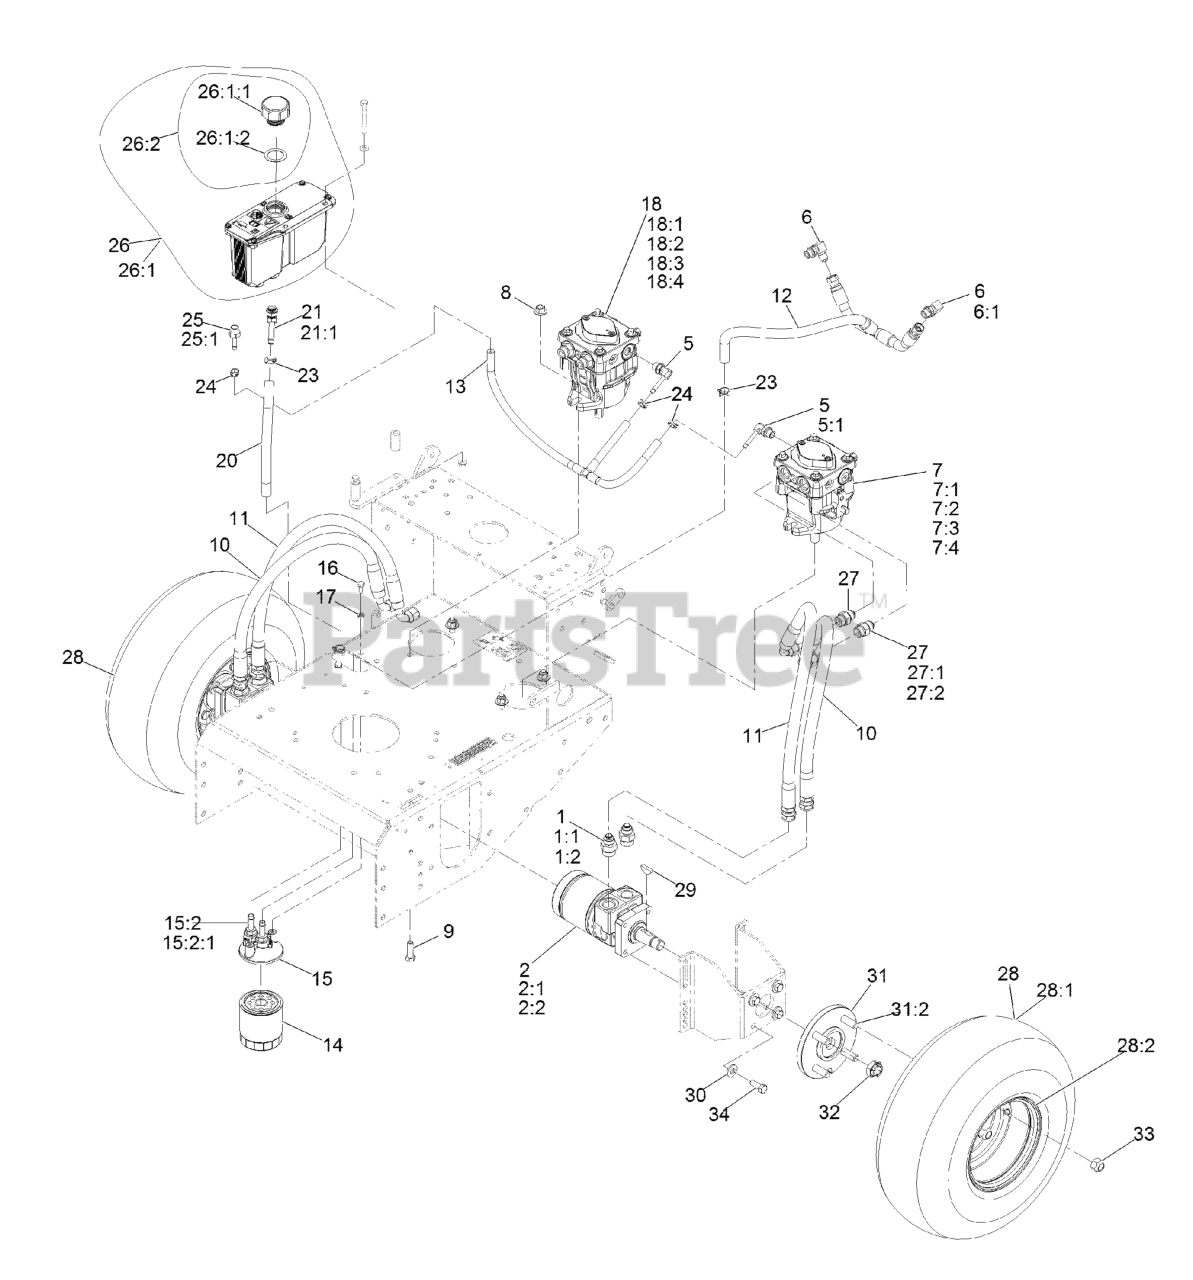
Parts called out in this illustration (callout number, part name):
1	FITTING-STRAIGHT
1:1	O-RING
2	HYD MOTOR ASM
2:1	SEAL KIT
2:2	BEARING AND SEAL KIT
5	ELBOW-90 DEG
5:1	O-RING
6	FITTING-ELBOW, 90 DEG
6:1	O-RING
7	LH HYD PUMP ASM
7:1	INPUT SHAFT KIT
7:2	BEARING-THRUST
7:3	CYLINDER BLOCK KIT
7:4	SEAL OVERHAUL KIT
8	NUT-FLANGE
9	SCREW-HH
10	HYD HOSE ASM
11	HYD HOSE ASM
12	CHARGE HOSE ASM
13	CASE DRAIN HOSE ASM
14	ELEMENT-FILTER, WINTER
14	FILTER-25 MICRON, BI-DIRECTIONAL
15	FILTER HEAD ASM
15:2	ADAPTER-STRAIGHT
15:2:1	O-RING
16	SCREW-HH
17	WASHER-LOCK
18	RH HYD PUMP ASM
18:1	INPUT SHAFT KIT
18:2	BEARING-THRUST
18:3	CYLINDER BLOCK KIT
18:4	SEAL OVERHAUL KIT
20	HOSE-CHARGE
21	FITTING-BARBED, 45 DEG
21:1	O-RING
23	CLAMP-HOSE
24	CLAMP-HOSE
25	ADAPTER-STRAIGHT
25:1	O-RING
26:1	Reservoir-HYD
26:1:1	Cap-Reservoir, HYD
26:1:2	GASKET-CAP
26:2	DECAL-WARNING
27	FITTING-STRAIGHT
28	WHEEL AND TIRE ASM
28:1	TIRE-TURFMASTER
28:2	RIM-WHEEL
29	KEY-WOODRUFF
30	WASHER-BELLEVILLE
31	WHEEL HUB ASM
31:2	STUD-WHEEL
32	NUT-LOCK
33	NUT-LUG
34	SCREW-HH
